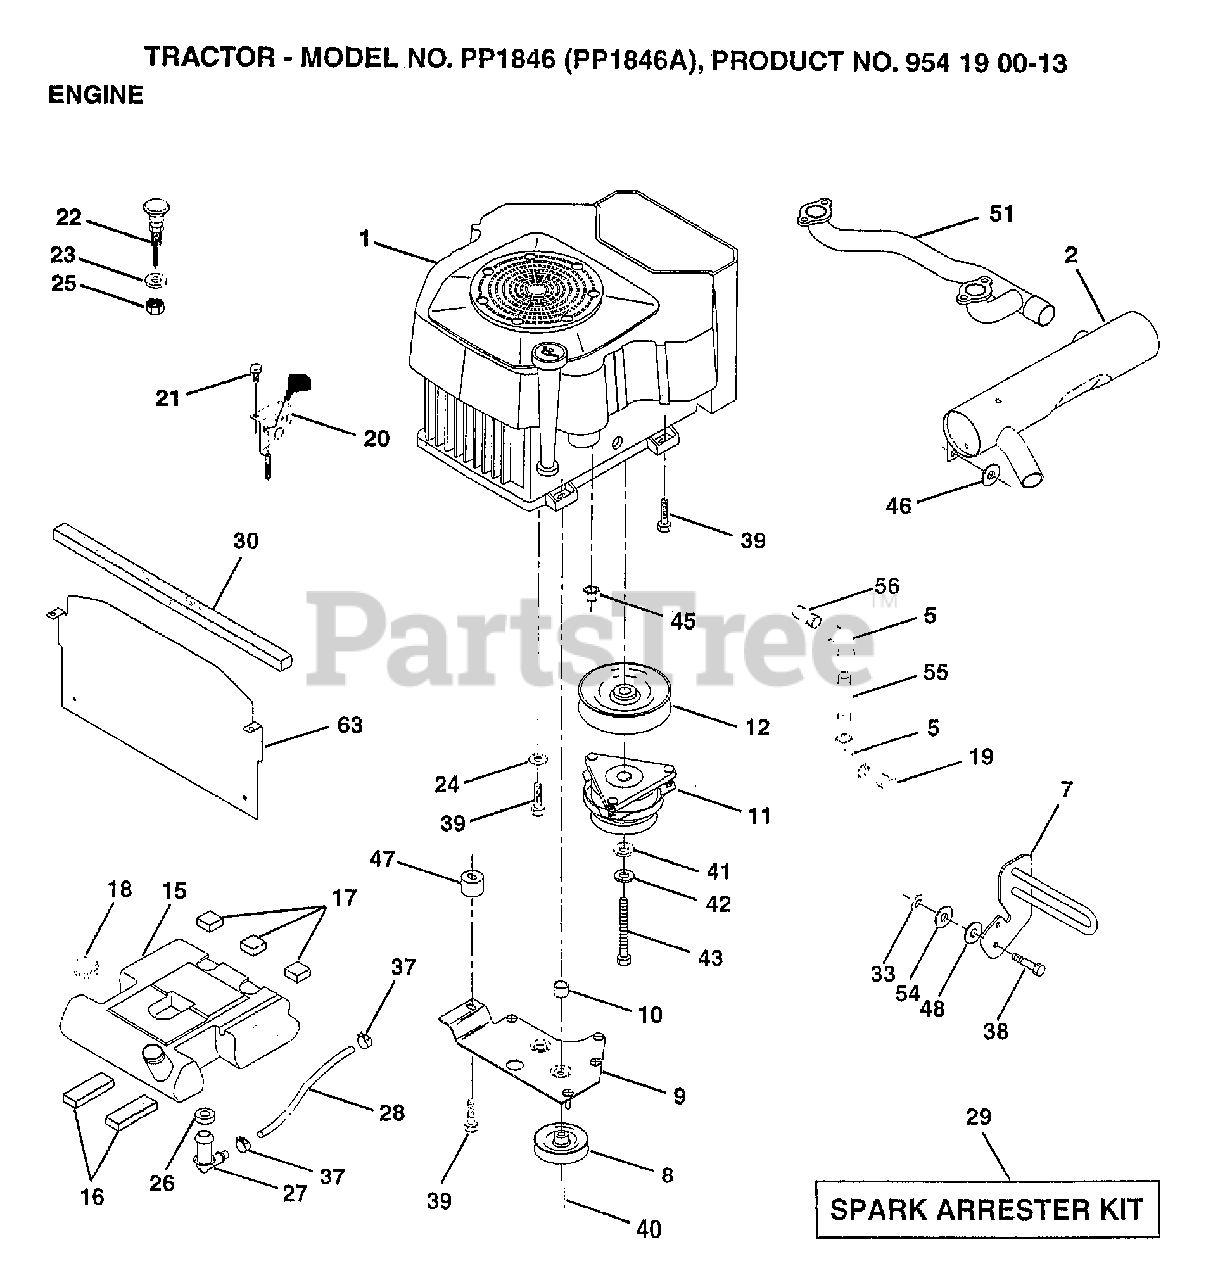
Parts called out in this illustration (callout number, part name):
1	ENGINE, KOHLER
5	ELBOW
7	GUARD.MUFFLER.ASM
9	KEEPER ASM BELT
10	BUSHING.
12	PULLEY.ENG.CLUTCH
15	TANK FUEL REAR
16	PAD IDLER TI
17	PAD-SPACER LT
18	CAP ASM FUEL
19	PLUG T
21	SCREW LT
22	CHOKE CONTROL
23	WASHER
24	LOCKWASHER
25	"NUT,KEPS 3/8-24IM"
26	BUSHING OUTLET T
27	STEM.TANK.FUEL
29	SPARK ARREST KIT
30	FOAM-STRIP LT
33	NUT
37	HOSE CLAMP
38	"BOLT,HEX"
39	SCREW.3/8-16X2.25
40	SCREW.TT.3/8-16X4
41	WASHER
42	LOCKWASHER
43	BOLT.7/16-20X4.25
45	NUT
46	WASHER HYT
47	SPACER.ENGINE
48	WASHER T
54	WASHER
56	NIPPLE.PIPE
63	HEAT.SHIELD.VGT.
